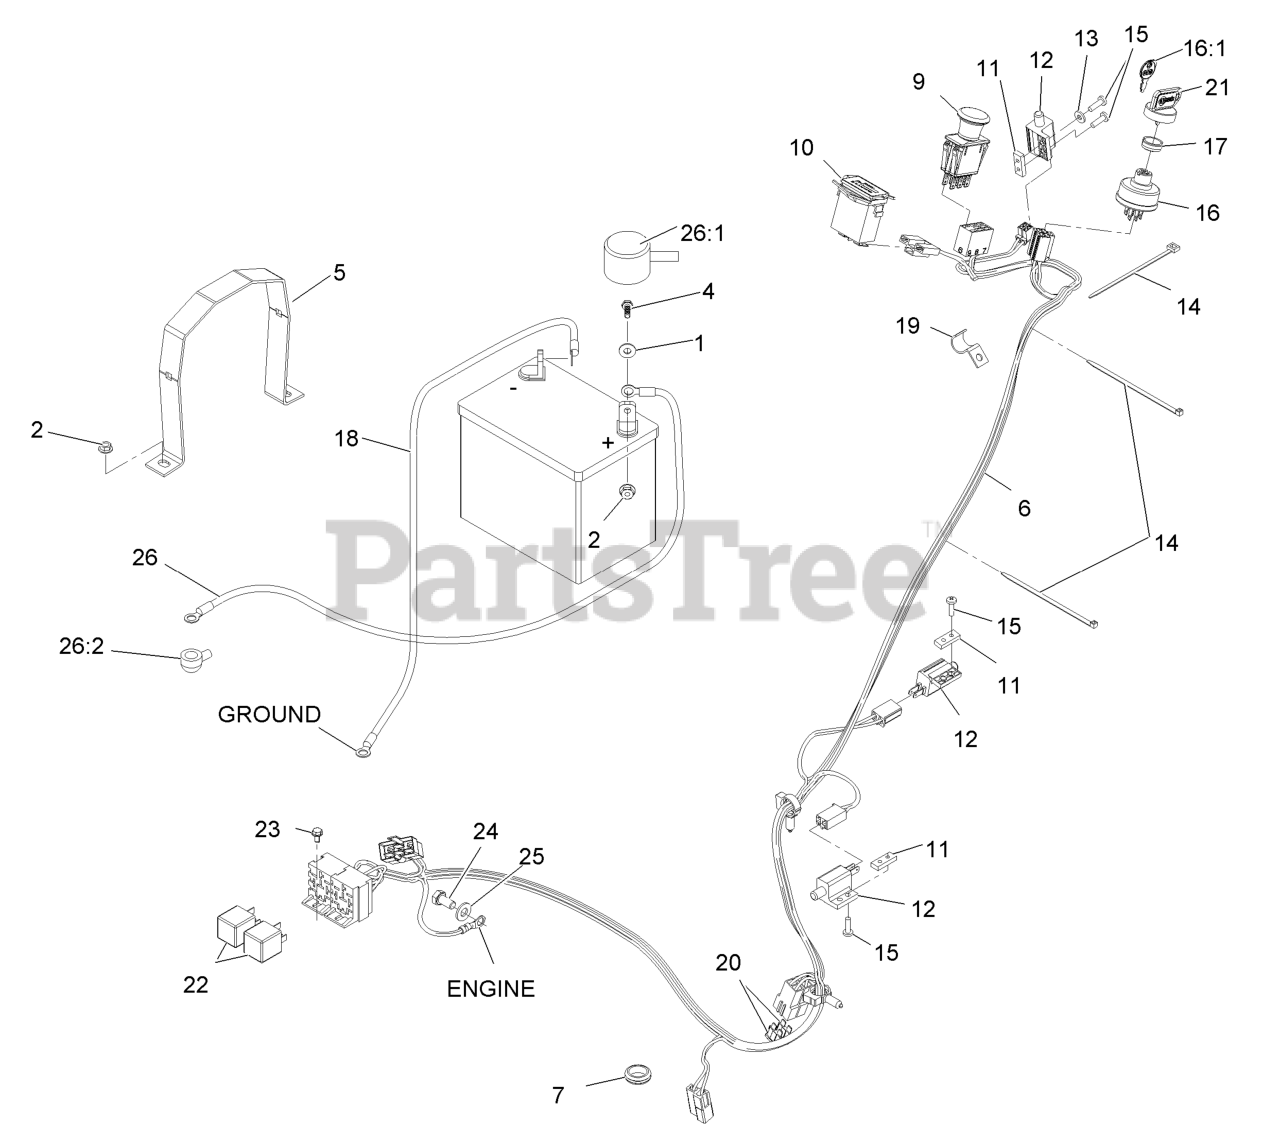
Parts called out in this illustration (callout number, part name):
1	WASHER-FLAT
4	SCREW-HH
5	STRAP,BATTERY HOLDDOWN
6	HARNESS-WIRE, TTX
7	GROMMET
9	SWITCH-PTO
10	METER-HOUR
11	PLATE-TAPPED
12	SWITCH-OPEN, NORMALLY
13	WASHER-FLAT
14	TIE-PLASTIC
15	SCREW-PPH
16:1	KEYS-IGNITION (SPARE PAIR
17	NUT-SWITCH, IGNITION
18	WIRE-GROUND
19	CLIP-HALF, LOOM
20	FUSE-BLADE TYPE, 20 AMP
21	KEY-IGNITION
23	SCREW-HWH
24	SCREW-HH
25	WASHER-PLAIN
26	POSITIVE BATTERY CABLE AS
26:1	INSULATOR-BATTERY
26:2	INSULATOR-SOLENOID
